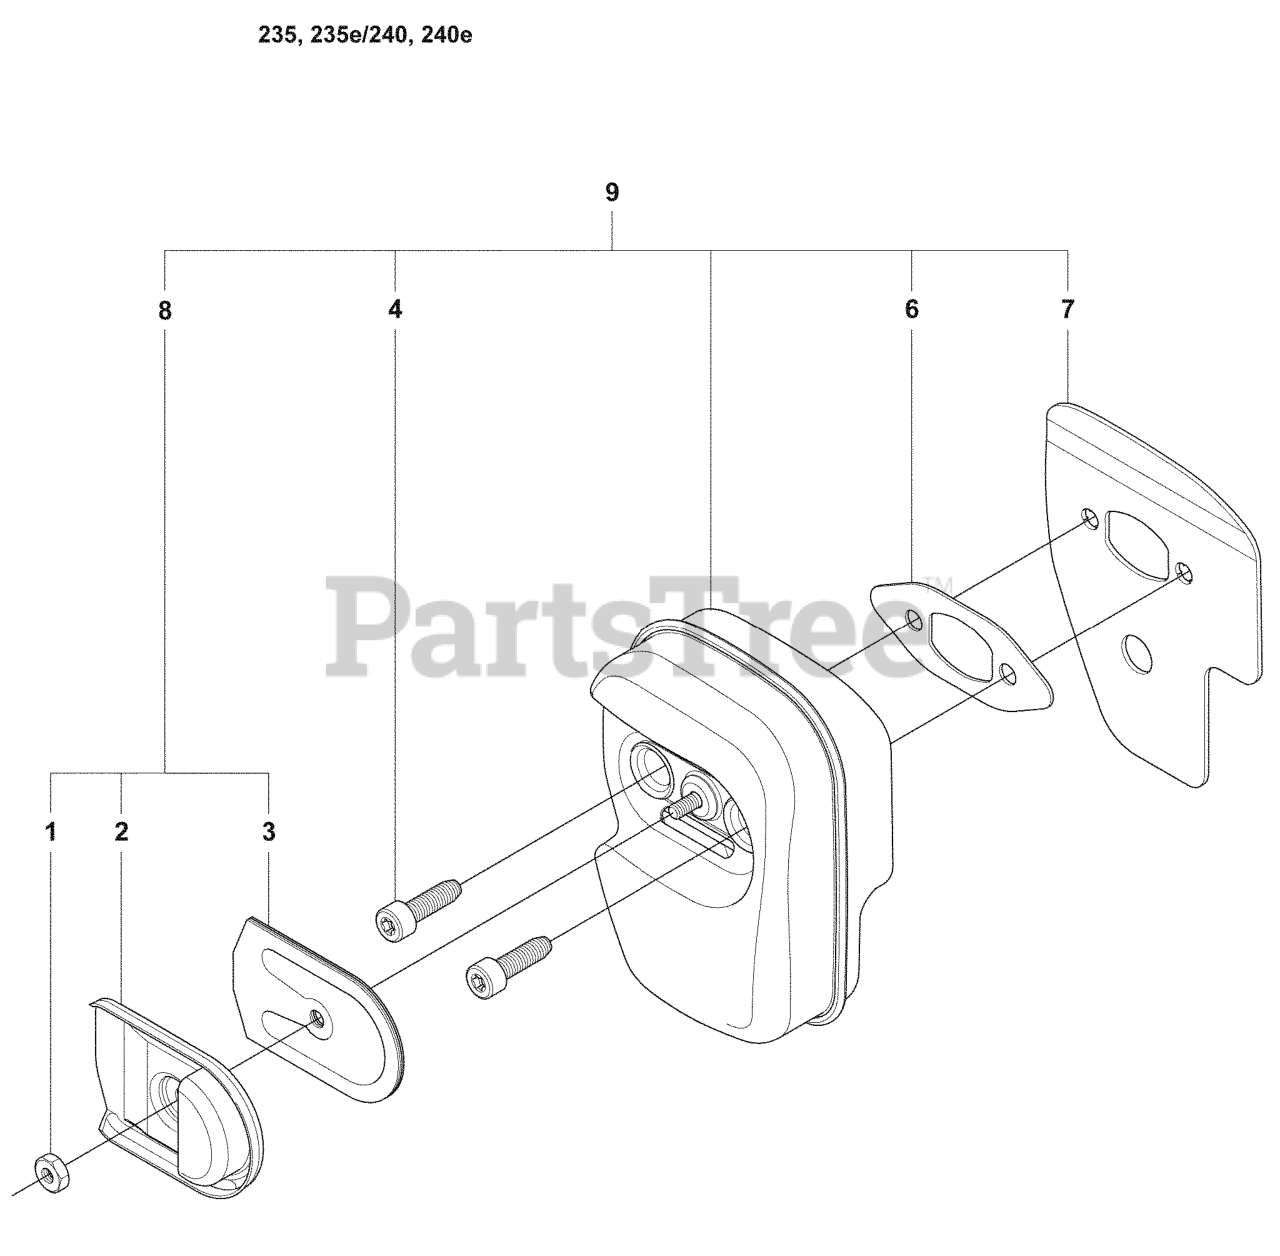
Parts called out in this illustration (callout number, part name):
1	NUT-BRASS
2	EXHAUST PLATE
3	SCREEN ARRESTOR
4	SCREW MUFFLER
8	KIT SPARK ARRESTOR
9	MUFFLER KIT
